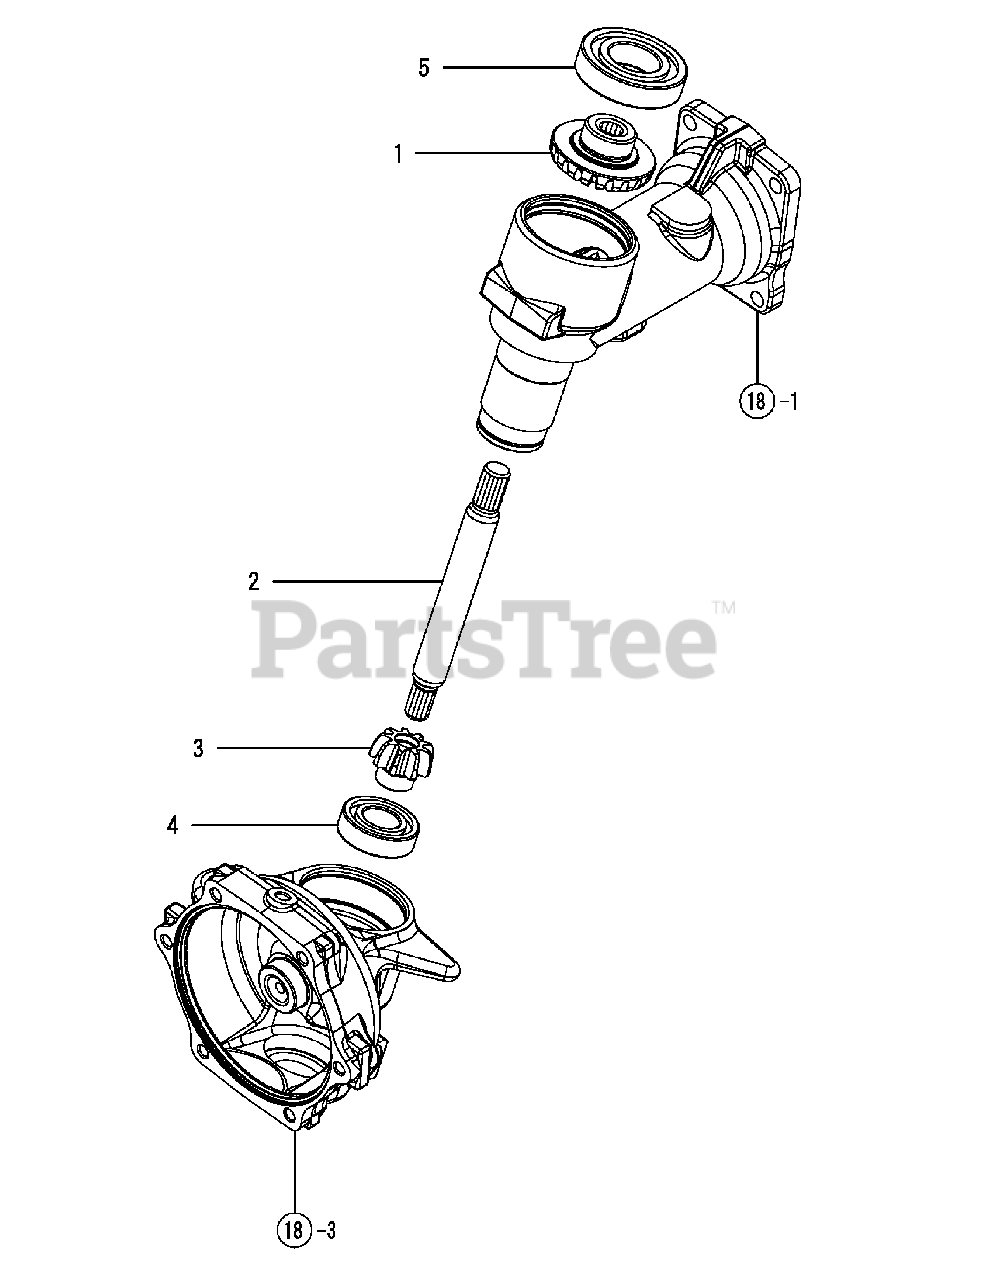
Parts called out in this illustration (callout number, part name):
1	GEAR 20T, BEVEL
2	SHAFT, FRONT 2
3	PINION F, FINAL
